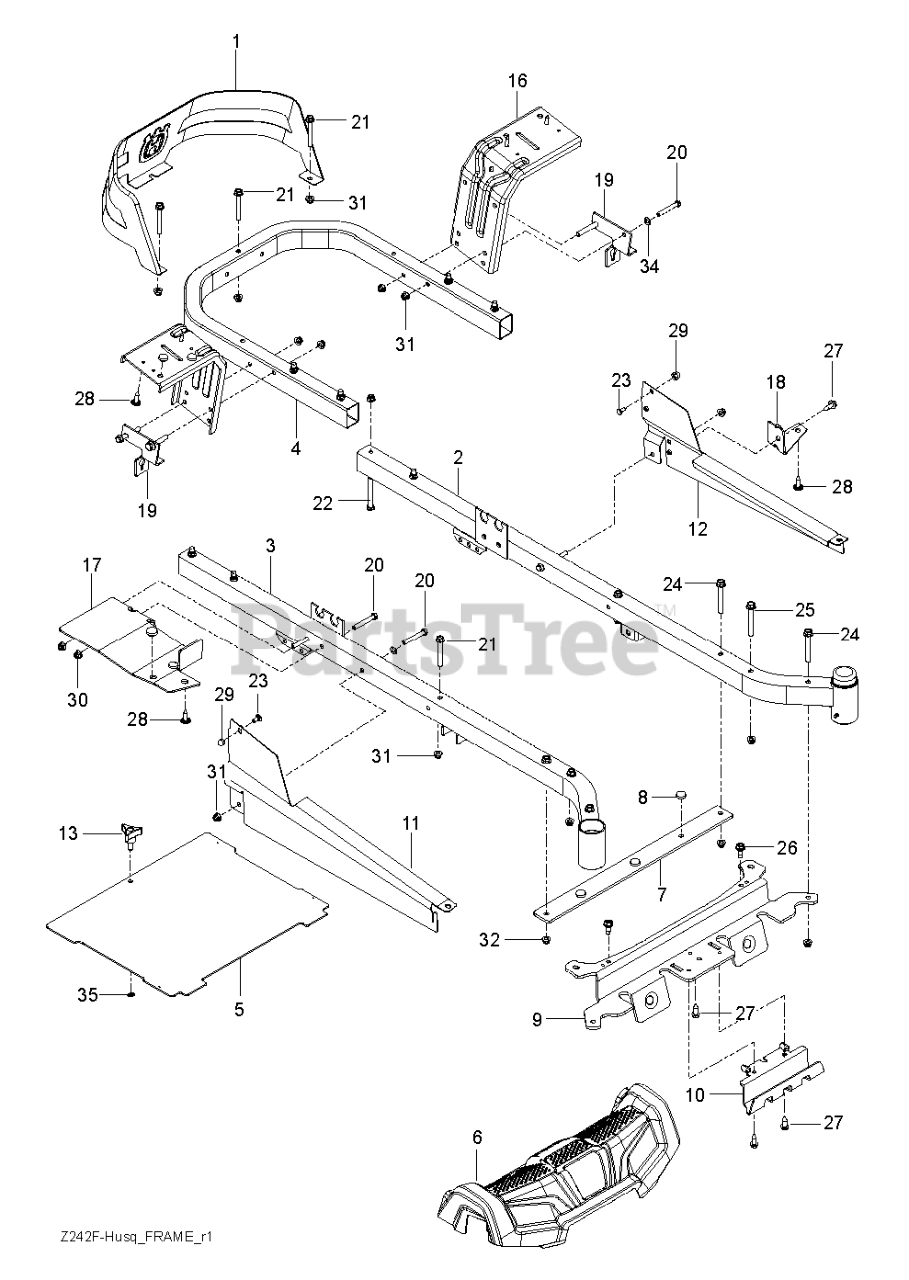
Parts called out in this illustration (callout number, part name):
1	GUARD.ENGINE.HUSQ.RZ.X498
2	FRAME.TUBE.RZ.MAIN.WELD.RH.ORG
3	FRAME.TUBE.RZ.MAIN.WELD.LH.ORG
4	TUBE.PNT.FRAME.RER.HUSQ.23".RZ
5	PLATE, FOOT W/DECALS RZ
6	COVER.FOOTREST.REFRESH.ASM
7	FOOTREST.PLATE.SUPPORT.X431
8	GROMMET.BUMPER
9	CROSS.PNT.MEMBER.BLK
10	SKID.PLATE.PNT.RZ.REF.SIVER
11	COVER.RAIL.RH.RZ.X668
12	COVER.RAIL.LH.RZ.X668
13	KNOB W/STUD
16	FENDER.SUPPORT.PNT.X431
17	SUPPORT.PNT.RH.CONSOLE.FRONT
18	SUPPORT.PNT.LH.CONSOLE.FRONT
19	BRKT ROD.BYPASS.EZT.X431
20	BOLT.FIN HEX 5/16-18UNC X2 1/4
21	BOLT HEX 5/16-18 GR 5
22	BOLT.HEX.FIN.3/8-16 X 3.GR5
23	BOLT.CARRIAGE.5/16-18.7/16
24	HHFS 3/8-16 X 3 GRD 5 ZD
25	BOLT SHOULDER,FLANGED,3/8-16X3
26	BOLT.5/16-18.THRD.ROLL.SHOULDR
27	BOLT.5/16HEX.WHS.HD
28	SCREW.#10 X 0.750.BOS
29	NUT ACORN,FLANGED,5/16-18
30	NUT LOCK HEX FLANGE 5/16-18
31	5/16-18 NYLOC FLANGE NUT
32	NUT 3/8-16 HEX FLG NYLOC ZD
34	WASHER
35	WASHER 5/16"
